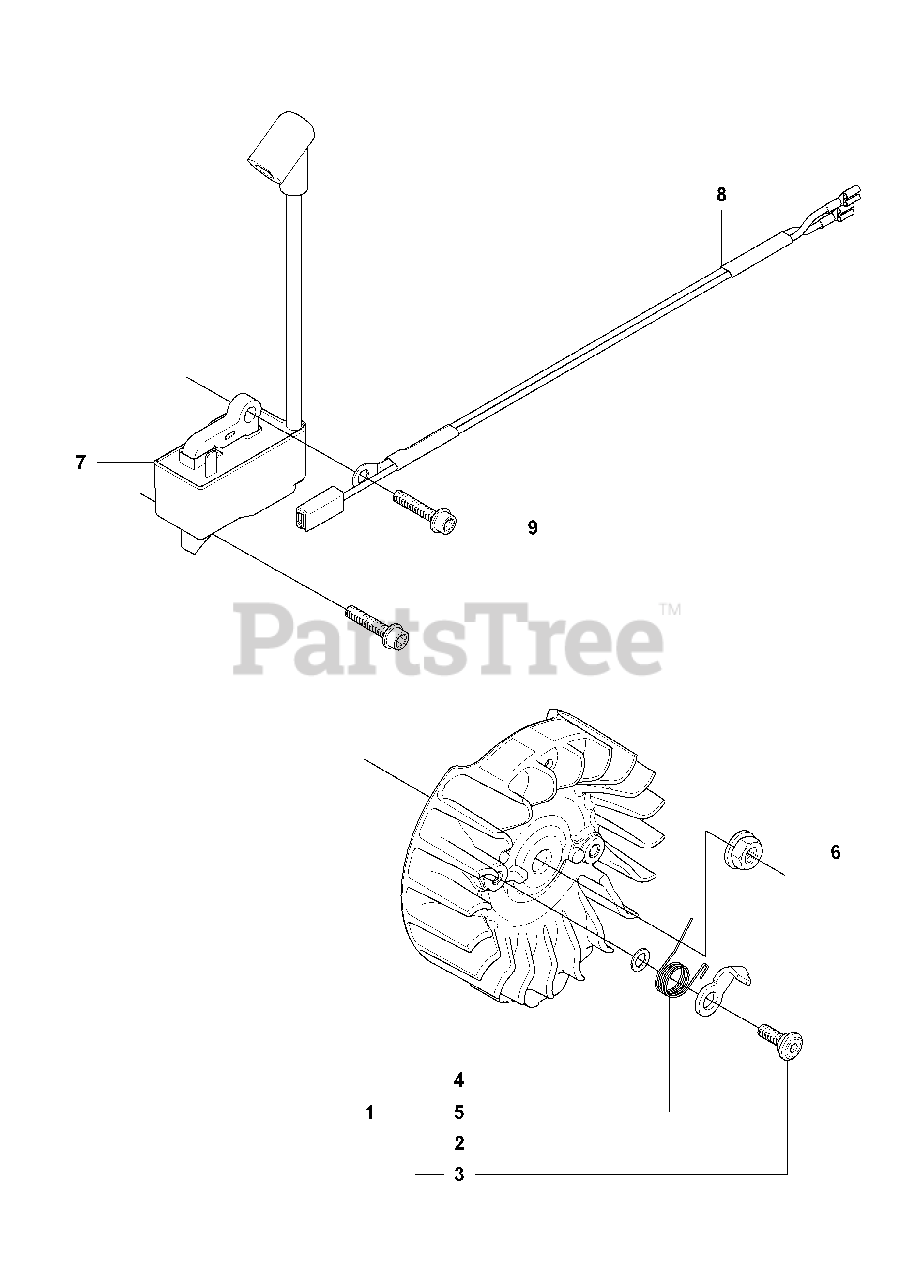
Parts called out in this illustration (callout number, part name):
1	FLYWHEEL ASSY
5	%SPRING, STARTER CATCH
6	NUT W/ WASHER
7	%IGNITION MODULE
8	%WIRING ASSY
